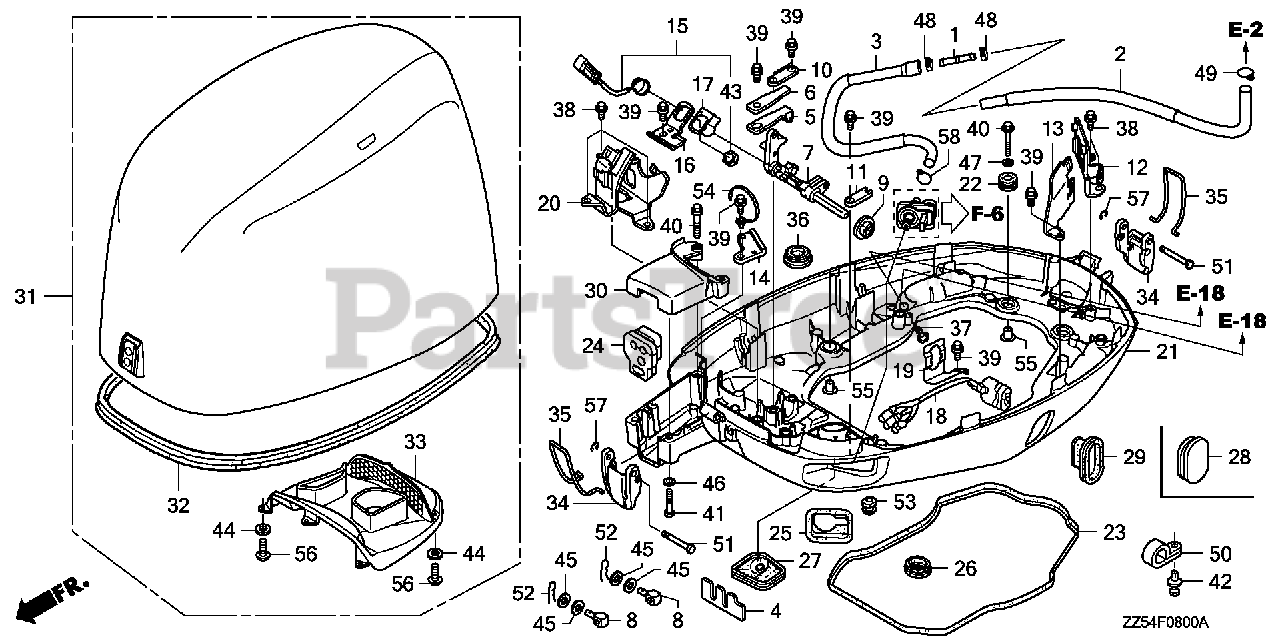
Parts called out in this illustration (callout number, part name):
1	JOINT, FUEL FEED HOSE
2	TUBE A, FUEL (FKM)
2	TUBE A, FUEL
3	TUBE D, FUEL (FKM)
3	TUBE D, FUEL
4	PLATE, REMOTE CONTROL CABLE
5	SPRING, CLICK
6	SPRING, CLICK ASSIST
7	SHAFT, SHIFT
8	PIVOT, SHIFT
9	BUSH, SHAFT
10	PLATE, SHIFT
11	PLATE, SHIFT SHAFT
12	BRACKET, REGULATOR
13	BRACKET B, CONNECTOR
14	BRACKET, CABLE CLIP
15	SWITCH SET, NEUTRAL
15	SWITCH ASSY., NEUTRAL
16	BRACKET, NEUTRAL SWITCH
17	PLATE, NEUTRAL SWITCH
18	SWITCH ASSY., POWER TILT
19	STAY, POWER TILT SWITCH
20	BRACKET, MAIN RELAY
21	CASE, ENGINE (LOWER) *NH282MU* (OYSTER SILVER METALLIC-U)
22	GROMMET, CASE (LOWER)
23	SEAL, CASE (LOWER)
24	GROMMET, CASE (LOWER) (A)
25	GROMMET, CASE (LOWER) (B)
26	GROMMET, CASE (LOWER) (C)
27	GROMMET, CASE (LOWER) (E)
29	GROMMET, CASE (LOWER) (G)
29	GROMMET, CASE (LOWER)
30	CASE, SEPARATE *NH282MU* (OYSTER SILVER METALLIC-U)
31	COVER, ENGINE *NH282MU* (OYSTER SILVER METALLIC-U)
32	SEAL, ENGINE COVER
33	GUIDE, ENGINE COVER AIR
34	LEVER, FASTENER
35	WIRE, FASTENER
36	CAP, L. SIDE COVER
37	GROMMET, WATER CHECK
38	BOLT, FLANGE (6X14) (CT200)
39	BOLT, FLANGE (6X12) (CT200)
40	BOLT, FLANGE (6X28)
41	BOLT, HEX. (6X40)
42	SCREW, RIVET (5X10)
43	NUT, HEX. (20MM)
44	WASHER, PLAIN (5MM)
45	WASHER, PLAIN (6MM)
46	WASHER, PLAIN (6MM)
47	WASHER, PLAIN (6MM)
48	CLAMP, TUBE (D12)
49	CLIP, TUBE (B12)
50	CLIP (14MM)
51	PIN (5X44.5)
52	PIN, LOCK SPECIAL (6MM)
54	CLIP, HARNESS BAND (155.3MM) (BLACK)
55	COLLAR, MODULE IGNITION CONTROL CASE (CDI)
56	SCREW, PAN (5X12)
57	E-RING (4MM)
58	CLIP, TUBE (ENGINE NO.)
58	CLIP, TUBE (B12) (ENGINE NO.)
59	SWITCH SET, NEUTRAL
